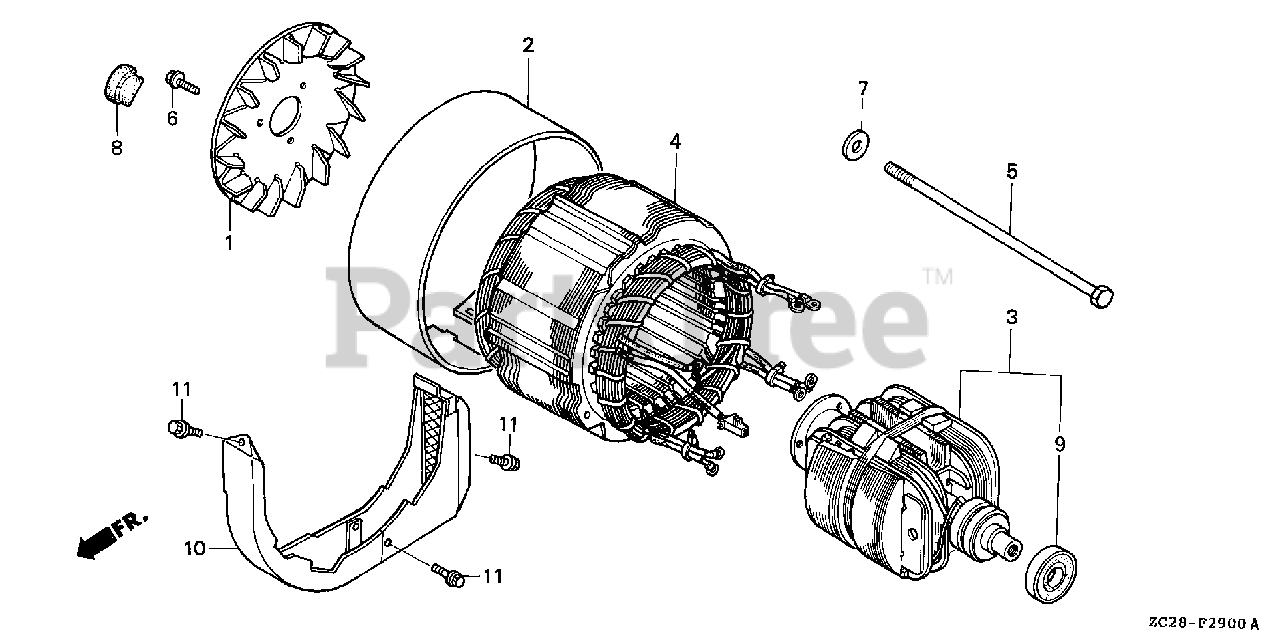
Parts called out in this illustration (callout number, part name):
1	FAN, GENERATOR COOLING
2	COVER, STATOR
4	STATOR ASSY. (120V/4KVA)
5	BOLT, HEX. (10X283)
6	SCREW, TAPPING (5X14)
7	WASHER (10.5MM)
8	GROMMET, CRANKCASE
9	BEARING ASSY. (6205)
10	COVER, DUCT
11	BOLT, FLANGE (5X10)
